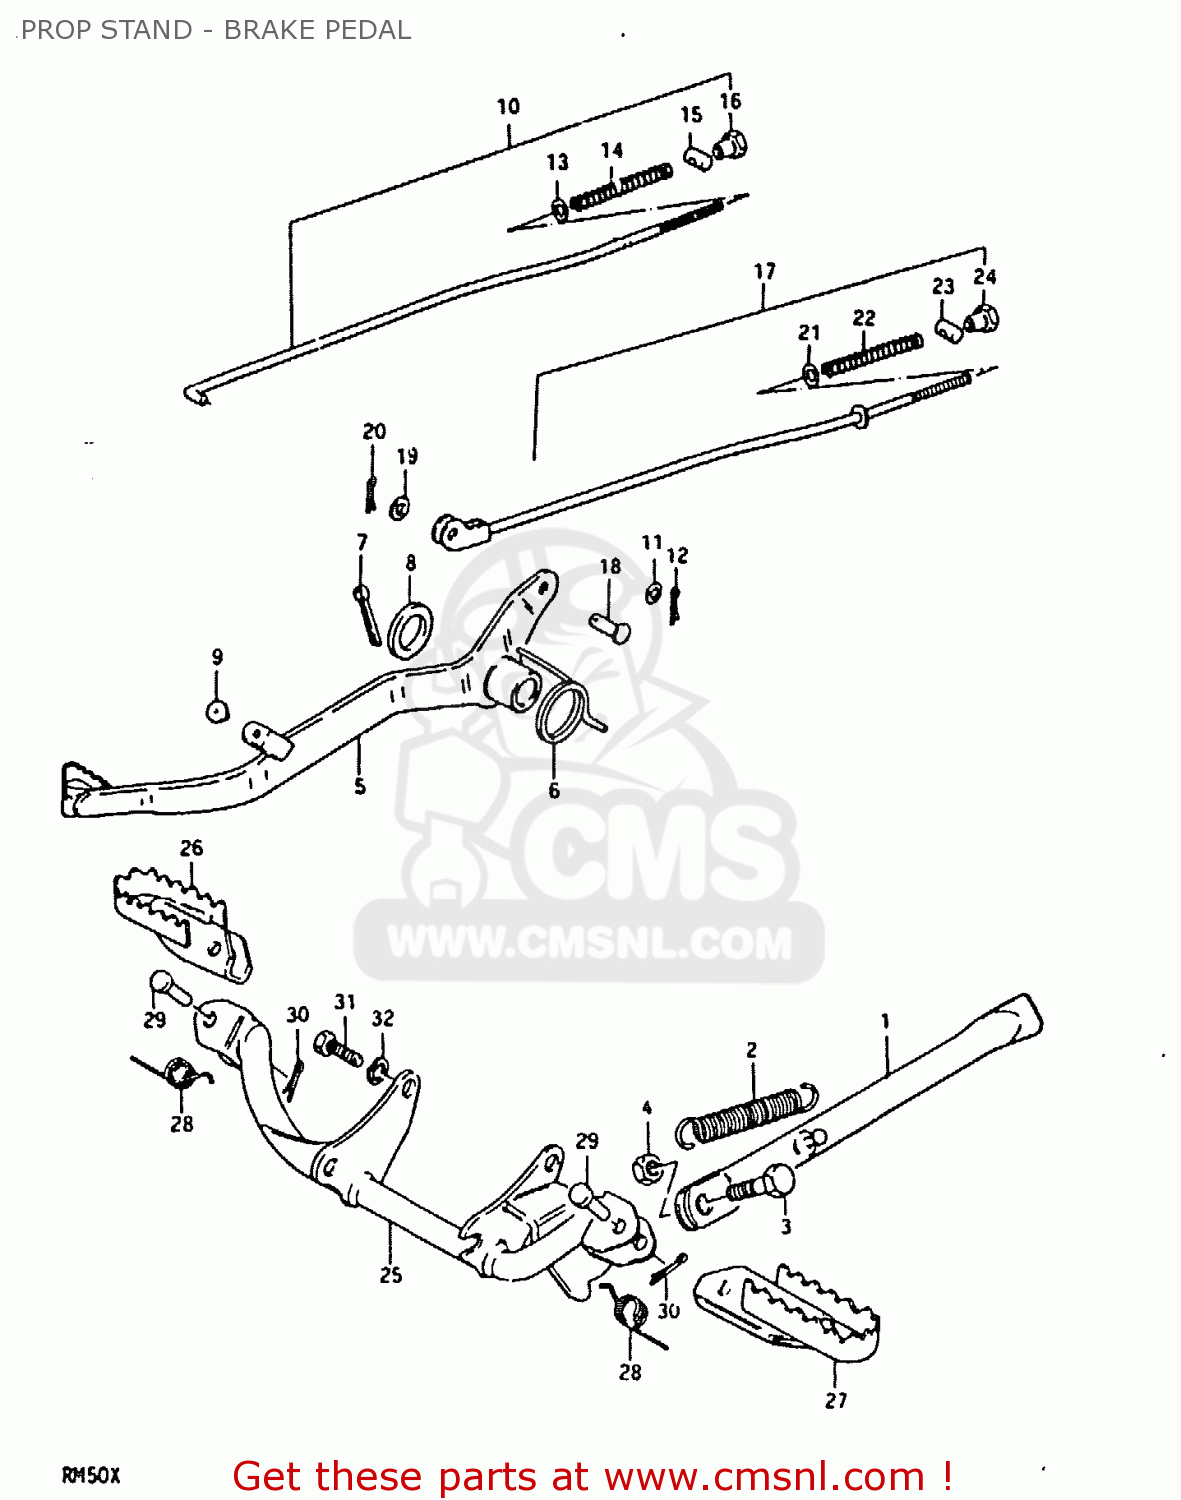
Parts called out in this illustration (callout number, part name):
1	STAND,SIDE
2	SPRING
3	BOLT
4	NUT
5	PEDAL,BRAKE
6	SPRING
7	COTTER PIN
8	WASHER(15.5X26X2.3)
9	STOPPER,BRAKE PEDAL
10	ROD ASSEMBLY,REAR BRAKE
11	WASHER
12	PIN 20X20
13	WASHER
14	SPRING
15	PIN(11X18)
16	NUT
17	ROD ASSEMBLY,REAR BRAKE
18	PIN(L:13.5)
19	WASHER
20	PIN 20X20
21	WASHER
22	SPRING
23	PIN(11X18)
24	NUT
25	BAR,FRONT FOOTREST
26	FOOTREST,FRONT,RIGHT
27	FOOTREST
28	SPRING
29	PIN
30	PIN 20X20
31	BOLT
32	LOCK WASHER
